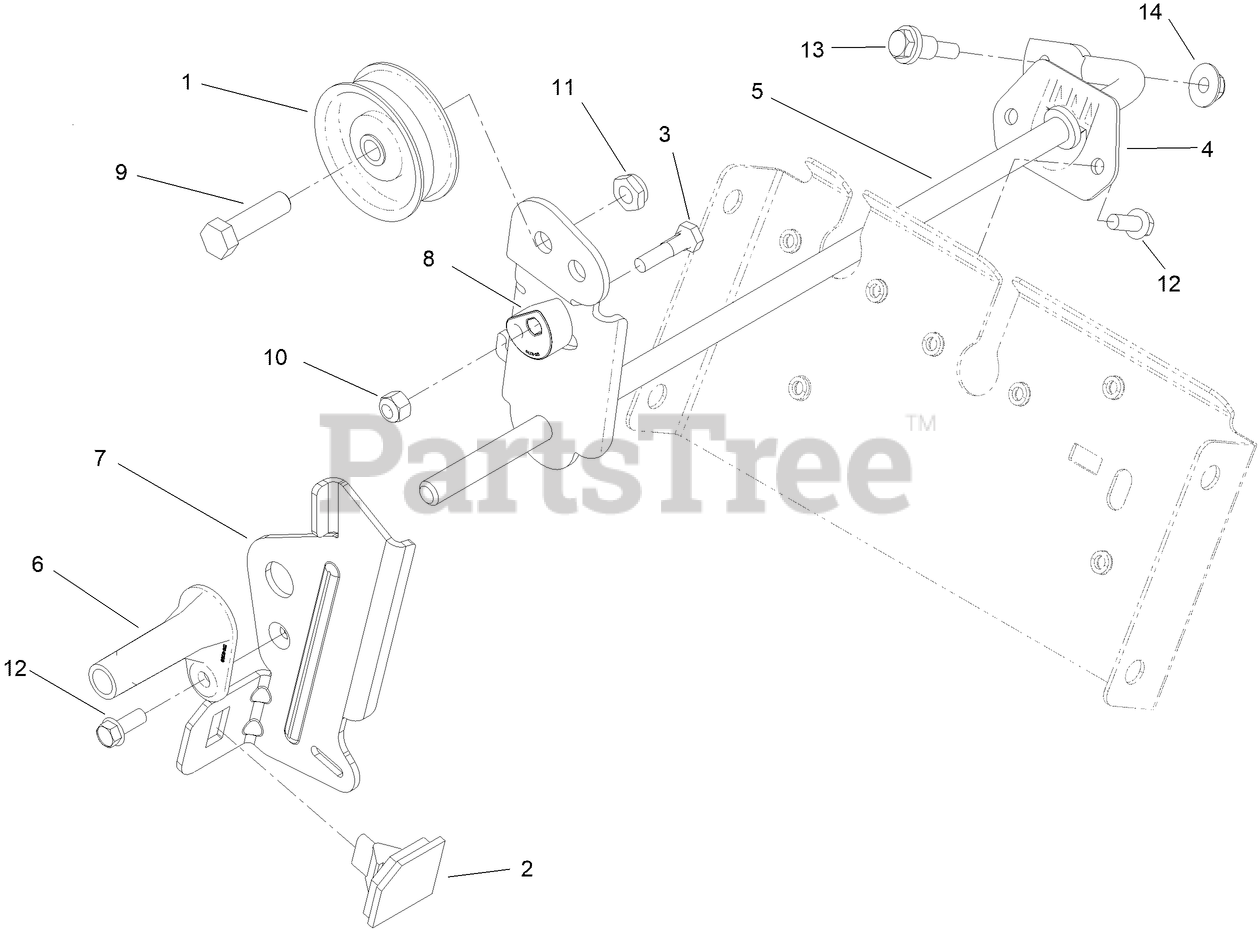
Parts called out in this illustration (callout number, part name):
1	PULLEY-IDLER
2	PAD-BRAKE
3	BOLT-PIVOT, ECCENTRIC
4	BUSHING-ROD, CLUTCH
5	IMPELLER CLUTCH ASM
6	PIVOT-BRAKE, IMPELLER
7	ARM-BRAKE, IMPELLER
8	ECCENTRIC-BRAKE, IMPELLER
9	SCREW-HH
10	NUT-HEX
11	NUT-HEX
12	SCREW-HWH
13	BOLT-SHOULDER
14	NUT-HF
